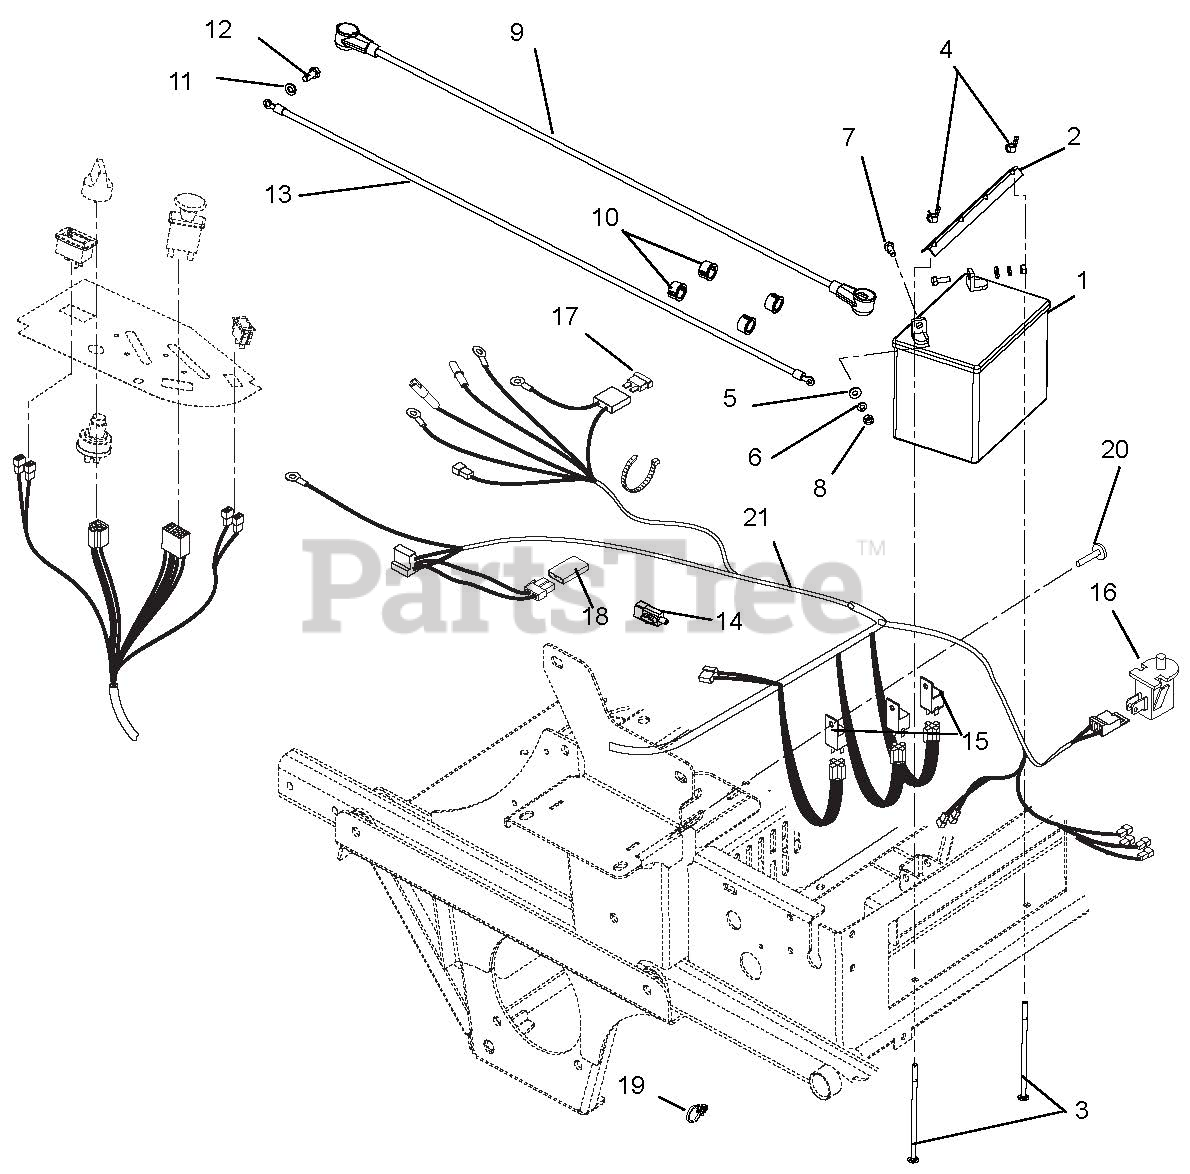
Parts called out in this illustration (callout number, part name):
1	Battery, SMF U1-9U1L/U1H
2	Hold Down
3	Bolt, Round Head Square Neck .25-20 x 7.50
4	Nut, Locking Wing .250-20
5	Washer, Flat-Steel .281 x .62 x .065
6	Washer, Locking .25 x .062 Regular
7	Bolt, Hex .25-20 x .75 Grade 5
8	Nut, Hex .25-20
9	Cable, POS Battery w/Boots 6 x 35
10	Bushing, Panel Snap .687 x .875 x .56
11	Washer, Locking .31 x .078 Regular
12	Bolt, Hex M8-1.25 x 20
13	Cable, Negative Battery 35.0"
14	Switch, Snap-In - N.O./N.O.
15	Relay
16	Switch, Snap Mounting
17	Fuse, 30 Amp
18	Diode, Connector Shell
19	Cable Tie with TREE (.25 HOLE)
20	Rivet, .25 Nylon Panel
21	Harness, Vertical A/C Wiring
21	Harness, Kohler EFI
